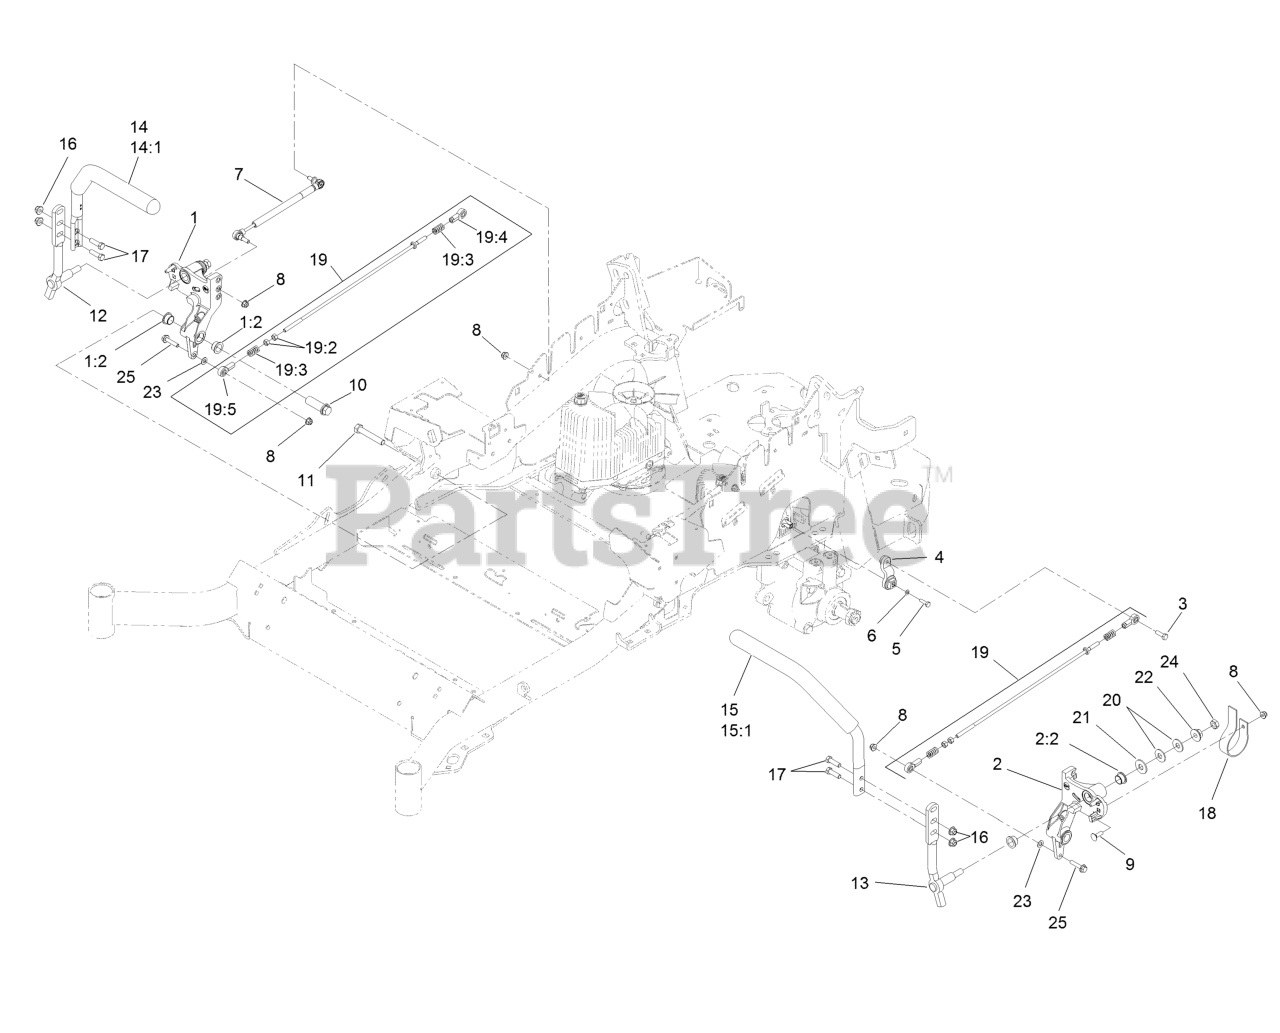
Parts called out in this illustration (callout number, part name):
1	RH MOTION CONTROL AND BUSHING ASM
1:2	BUSHING-FLANGE
2	LH MOTION CONTROL AND BUSHING ASM
2:2	BUSHING-FLANGE
3	SCREW-HH, THREAD LOCKING
4	ARM-CONTROL, PUMP
5	SCREW-HH
6	WASHER-SPRING
7	DAMPER-CONTROL, MOTION
8	NUT-HF, NI
9	BOLT-CARR
10	HUB-THREADED
11	SCREW-HH
12	LEVER-CONTROL MOTION, RH
13	LEVER-CONTROL MOTION, LH
14	RH STEERING HANDLE ASM
14:1	GRIP-LEVER, CONTROL
15	LH STEERING HANDLE ASM
15:1	GRIP-LEVER, CONTROL
16	NUT-HF, NI
17	SCREW-HH
18	SPRING-LEAF
19	PUMP LINKAGE REAR ASM
19:2	NUT-HEX
19:3	SPRING-COMPRESSION
19:4	BALLJOINT-LH
19:5	BALLJOINT-RH
20	WASHER-SPRING
21	WASHER-FLAT
23	WASHER-PLAIN
24	NUT-JAM
25	SCREW-HHF
